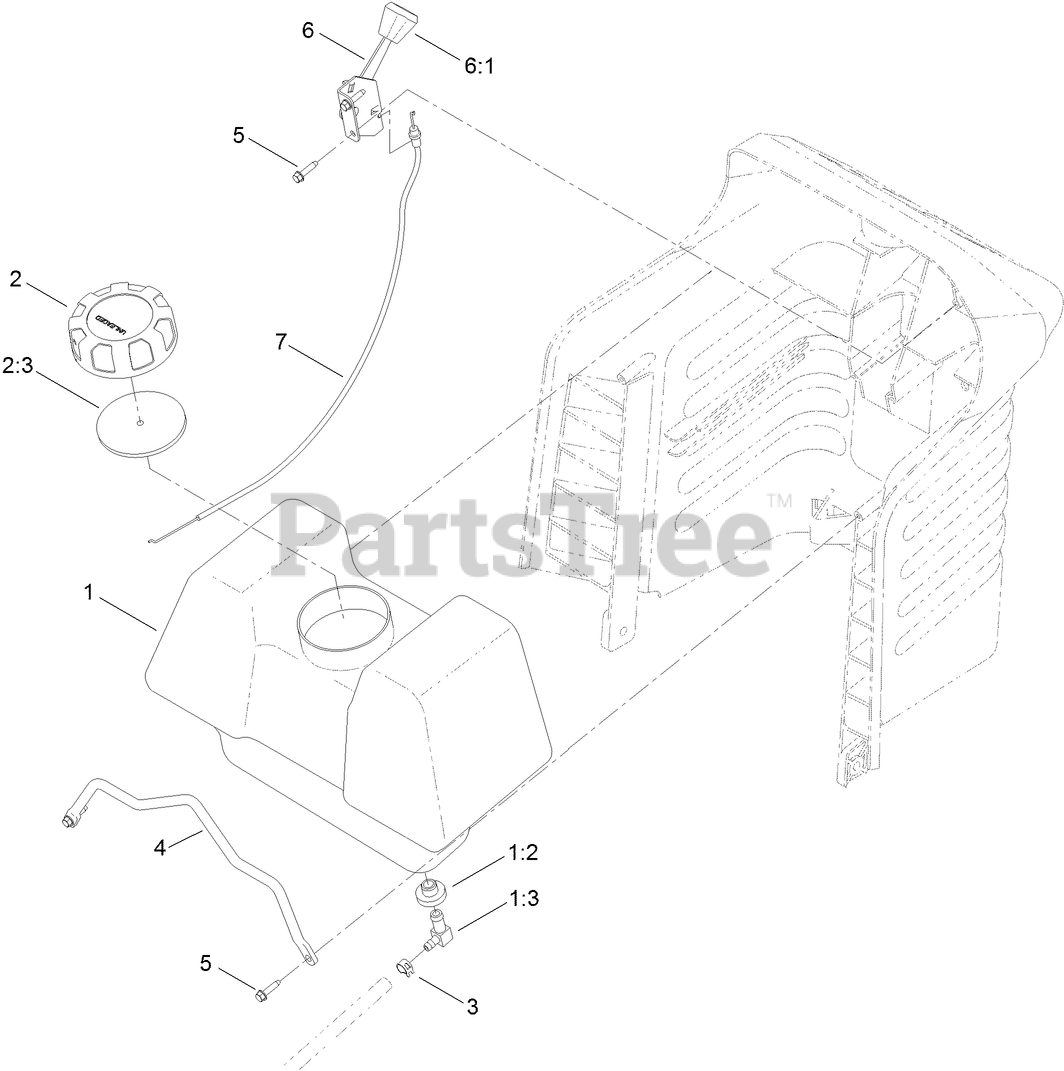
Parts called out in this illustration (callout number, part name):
1	GAS TANK ASM
1:2	BUSHING
1:3	VALVE-FUEL
2	GAS CAP ASM
2:3	GASKET-CAP, GAS
3	CLAMP-HOSE
4	ROD-TANK, GAS
5	SCREW-SPECIAL
6	THROTTLE CONTROL ASM
7	CABLE-THROTTLE
